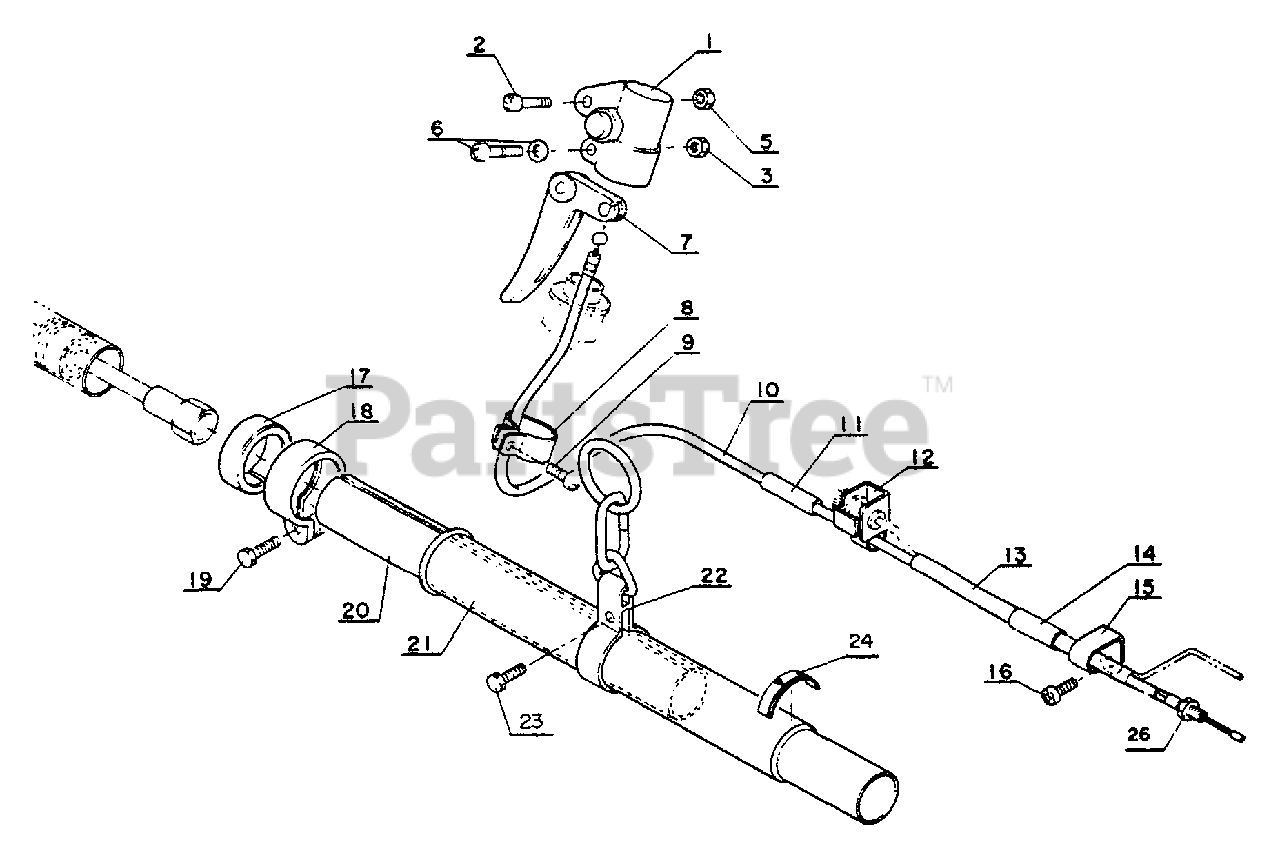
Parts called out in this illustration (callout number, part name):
1	CLAMP, THROTTLE CONTROL
2	SCREW - 5X30
5	LOCKNUT - 5
6	SCREW - 5X28
7	TRIGGER, THROTTLE
9	SCREW - 5X10
10	CABLE, THROTTLE
11	TUBE
12	CLIP
14	TUBE
15	CLAMP
16	SCREW - 5X8
17	SPACER
18	CLAMP
19	BOLT - 5X16
20	BUSHING
21	SWIVEL
22	SRM-202FA (Obsolete)
23	BOLT - 5X12
24	LABEL - ALIGNMENT
